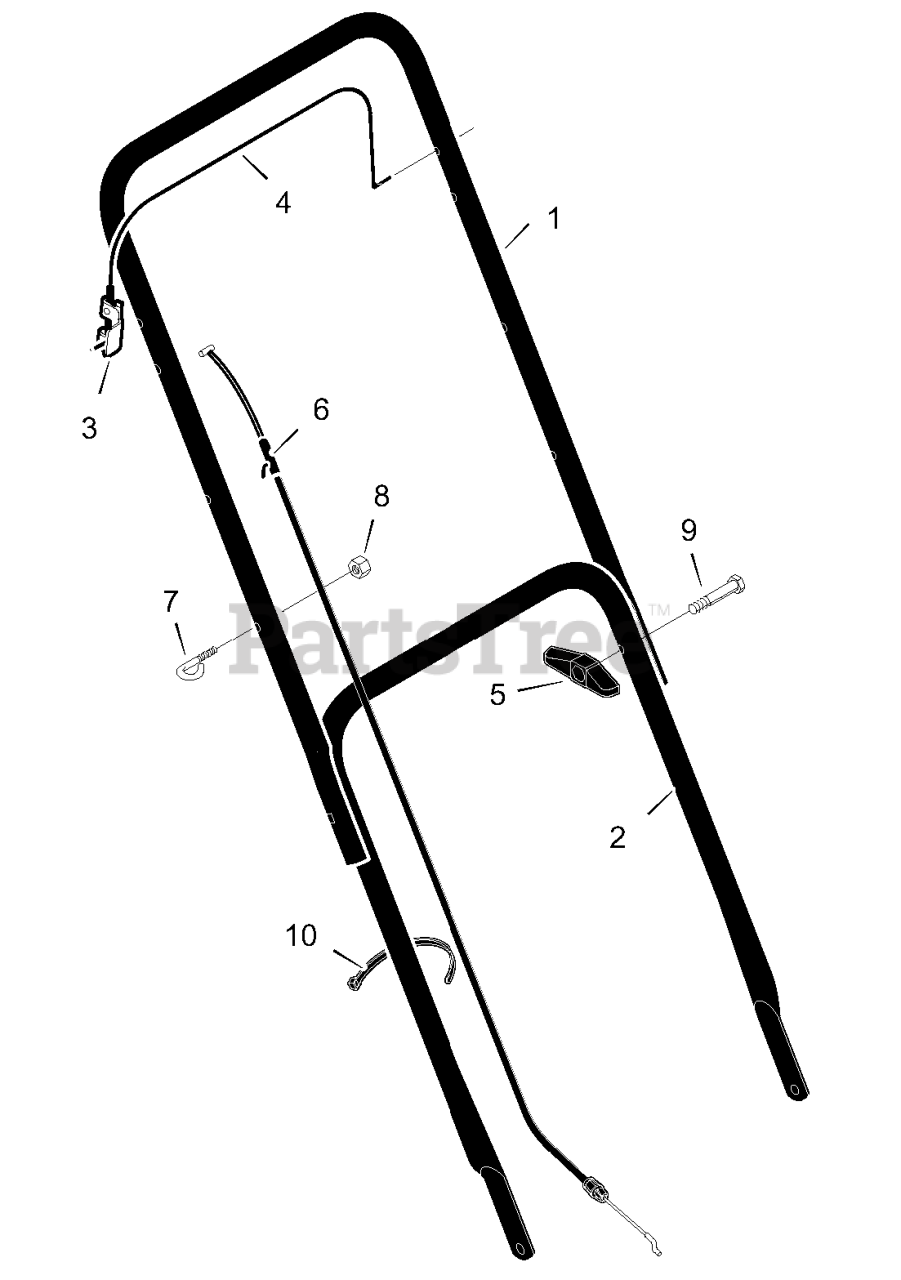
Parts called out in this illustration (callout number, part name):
1	Handle, Upper (Black)
2	Handle, Lower (Black)
3	Bracket, Stop Lever
4	Lever, Stop
5	Knob, Plastic
6	Engine Stop Cable
7	Guide, Rope
8	Locknut
10	Fastener, Cable
